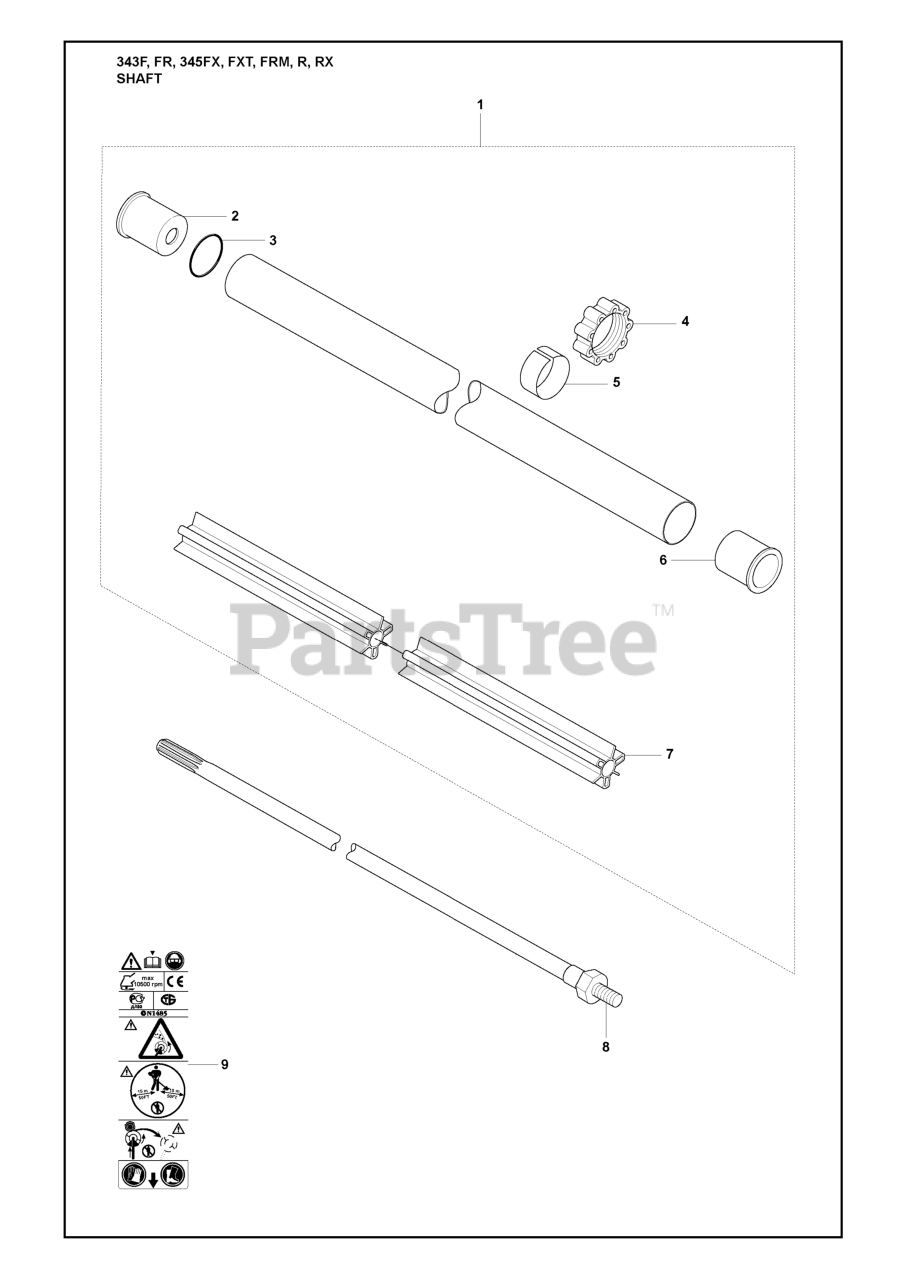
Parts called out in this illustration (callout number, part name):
1	TUBE
1	RP DRIVE SHAFT TUBE
2	SPACER SLEEVE
4	MOVEMENT LIMITER
5	%BAND
6	SPACER SLEEVE
7	GUIDE
8	SHAFT
8	DRIVE SHAFT
9	WARNING DECAL
